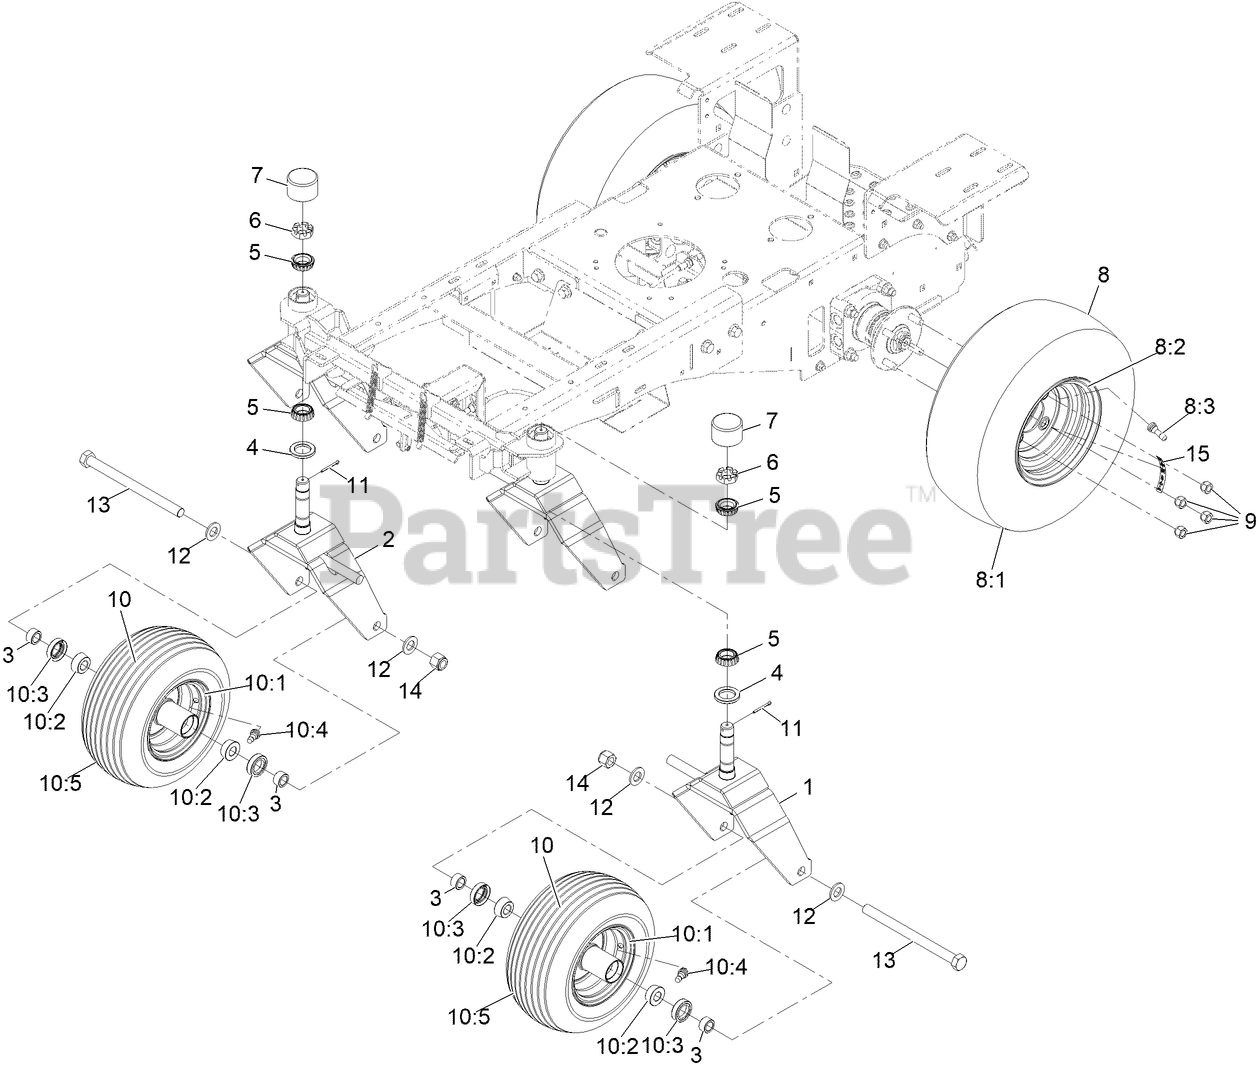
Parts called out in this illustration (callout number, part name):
1	Wld, Caster, L, Jr36, 36R
2	Wld, Caster, R, Jr36, 36R
3	SPACER-AXLE
4	SEAL-GREASE
5	CONE-BEARING, OUTER
6	NUT-SHH
7	CAP-DUST, RUBBER
8	TIRE/RIM ASM
8:2	Rim-8X5.375, Centered
8:3	Stem-Valve
9	NUT-LUG
10	WHEEL AND TIRE
10:1	VALVE
10:2	Rim-6 X 4.5
10:3	Tire-Rib
10:4	SEAL-CASTER
10:5	BEARING-CONE, TAPERED ROLLER
11	Pin-Cotter
12	WASHER-FLAT
13	SCREW-HH
14	NUT-LOCK, NI
15	DECAL-TORQUE, WHEEL HUB LUG
